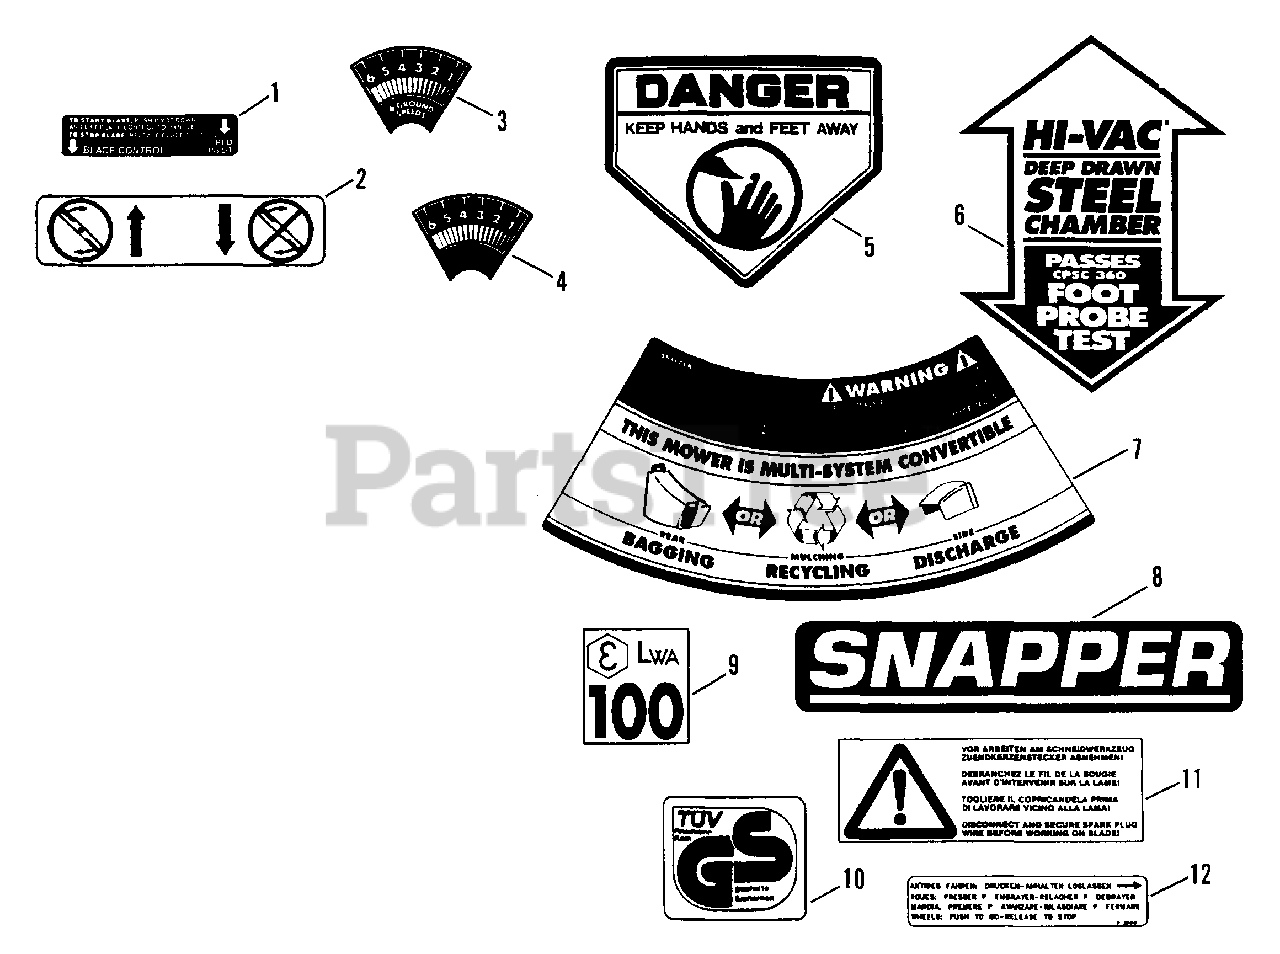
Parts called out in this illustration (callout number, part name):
1	DECAL, Blade Control (BBC)
2	DECAL, Blade Control
3	DECAL, Speed Sector
4	DECAL, Speed Sector
5	DECAL, DANGER (Keep Hands & Feet Away)
6	DECAL, Hi-Vac/Foot Probe
7	DECAL, Serial Blank (Large)
8	LOGO, SNAPPER, 7.31" (Molded)
9	DECAL, Noise Control
10	DECAL (GS)
11	DECAL, Spark Plug
12	DECAL, Wheel Control
